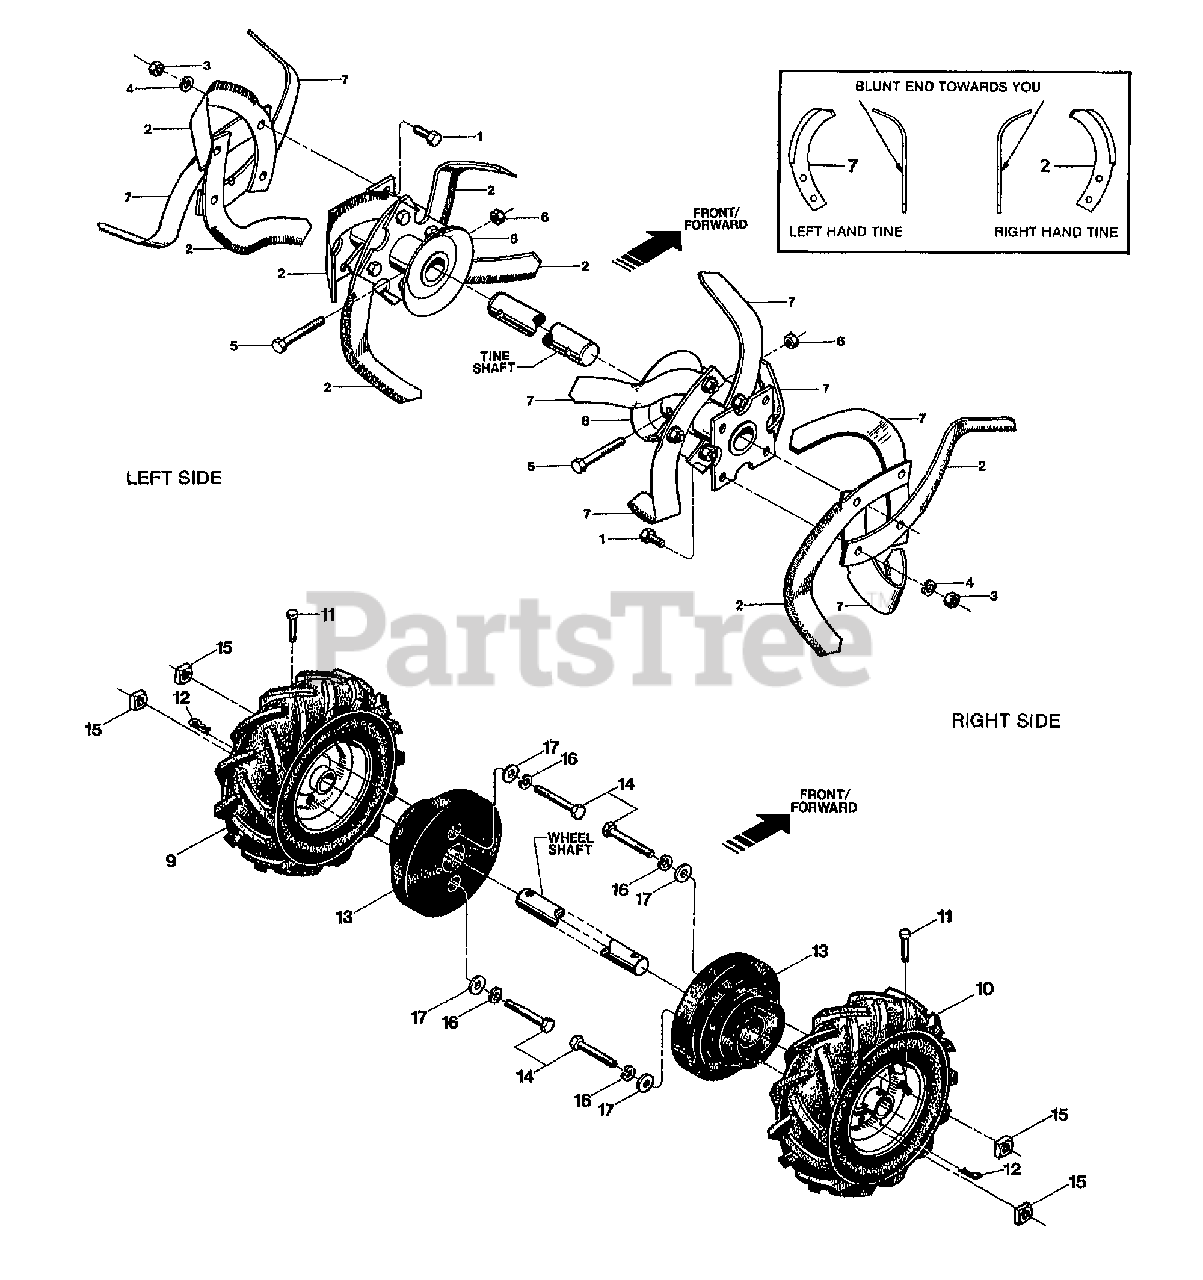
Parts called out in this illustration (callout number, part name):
1	SCR-HH 3/8-16X1.0 G5 ZP
1	SCR-HH 3/8-16X1-1/4" G5 ZP (1501004 & UP)
2	TINE-BOLO RT W/HDW
3	NUT-LOCK 3/8-16
4	WASHER-LK .375 @ DEPL
5	SCR-HH 3/8-16X2.00 G8
6	NUT-H/LK 3/8-16
7	TINE-BOLO LT W/HDW
8	WELD-TINE HOLDER ECONO (USE W/1.00" O.D. TINESHAFTS)
8	HOLDER-TINE ECONO RED (USE W/15/16" O.D. TINESHAFT)
9	ASSM-TIRE&WHEEL LH GRAY (15-20 LBS AIR REQ'D)
10	ASSM-TIRE&WHEEL RH GRAY (15-20 LBS AIR REQ'D)
11	PIN-CLEVIS
12	PIN-CLIP .08
13	WEIGHT-WHEEL
14	SCR-HH 3/8-16X3.0 G5 ZP
15	NUT-SQ 3/8-16
16	WASHER-LK .375 @ DEPL
17	WASHER-FLAT 3/8 SAE
